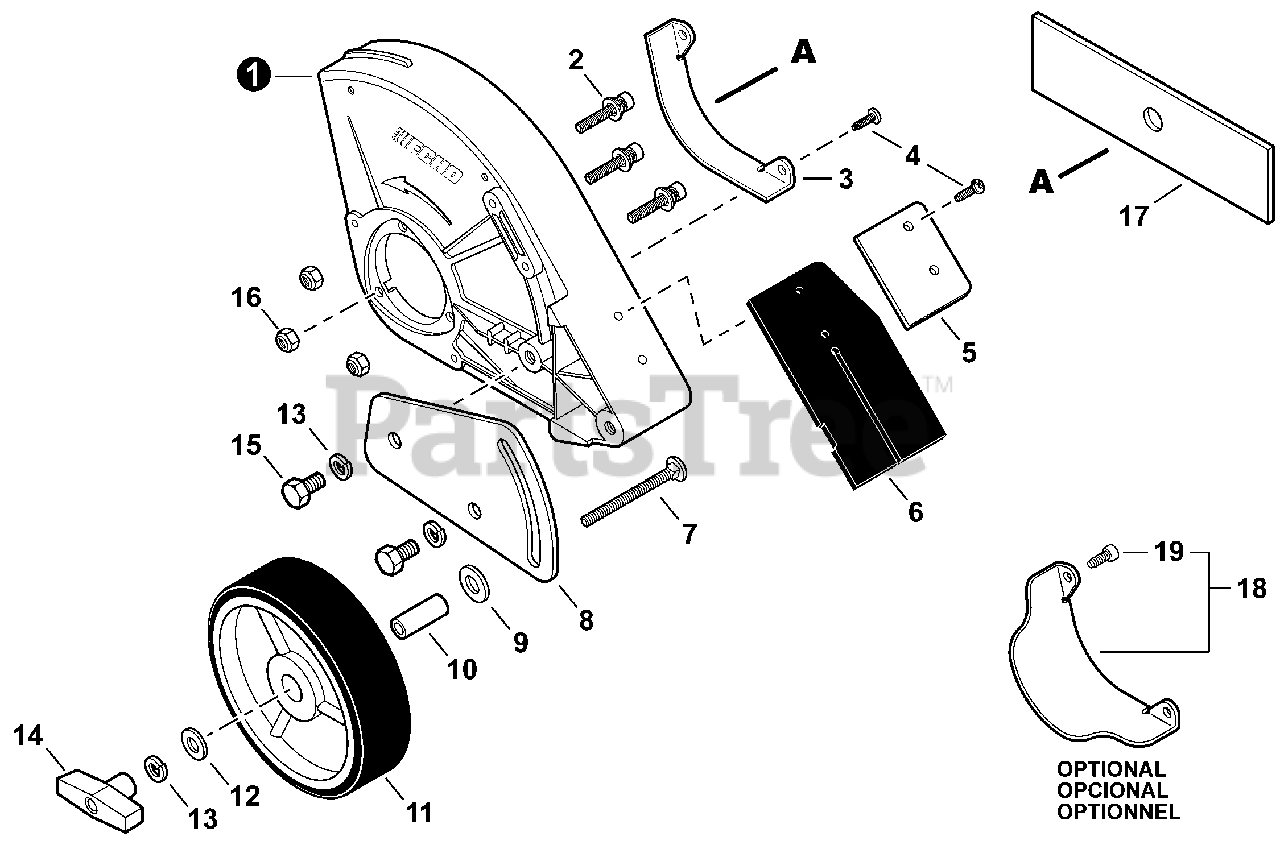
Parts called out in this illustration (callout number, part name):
1	SHIELD, BLADE
2	BOLT 5×25
3	GUARD, SHIELD
4	SCREW 4×12
5	PLATE, FLAP
6	FLAP, DEBRIS
7	BOLT 5/16"-18×2-1/2"
8	BRACKET, WHEEL
9	WASHER 10
10	COLLAR 12
11	WHEEL
12	WASHER 8
13	WASHER, SPRING 8
14	KNOB, FASTENER
15	BOLT 8×14
16	NUT, LOCK M5
17	BLADE - 2 PK
